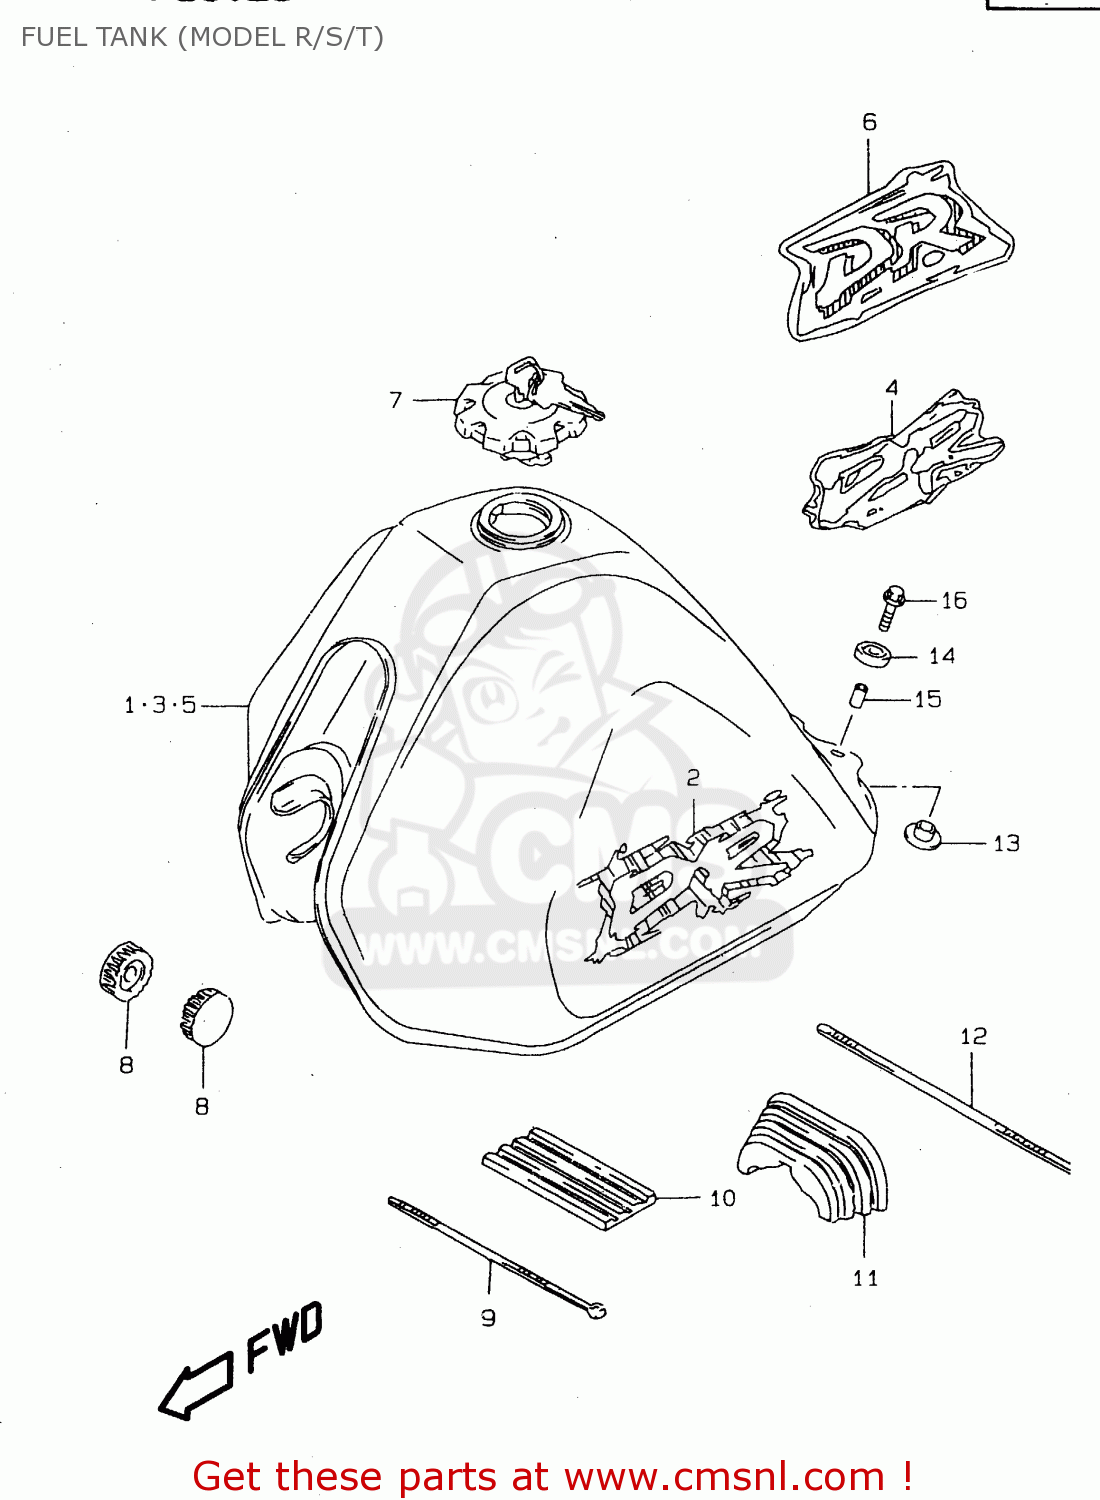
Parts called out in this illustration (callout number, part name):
1	TANK ASSEMBLY,FUEL
2	EMBLEM SET,FUEL TANK
3	TANK ASSEMBLY,FUEL
4	EMBLEM SET,FUEL TANK
5	TANK ASSEMBLY,FUEL
6	EMBLEM SET,FUEL TANK
7	CAP SET,FUEL TANK
8	CUSHION
9	CLAMP
10	CUSHION,FUEL TANK UPR FR
11	CUSHION,FUEL TANK RR
12	CLAMP(L:300)
13	CUSHION
14	CUSHION
15	SPACER
16	BOLT
